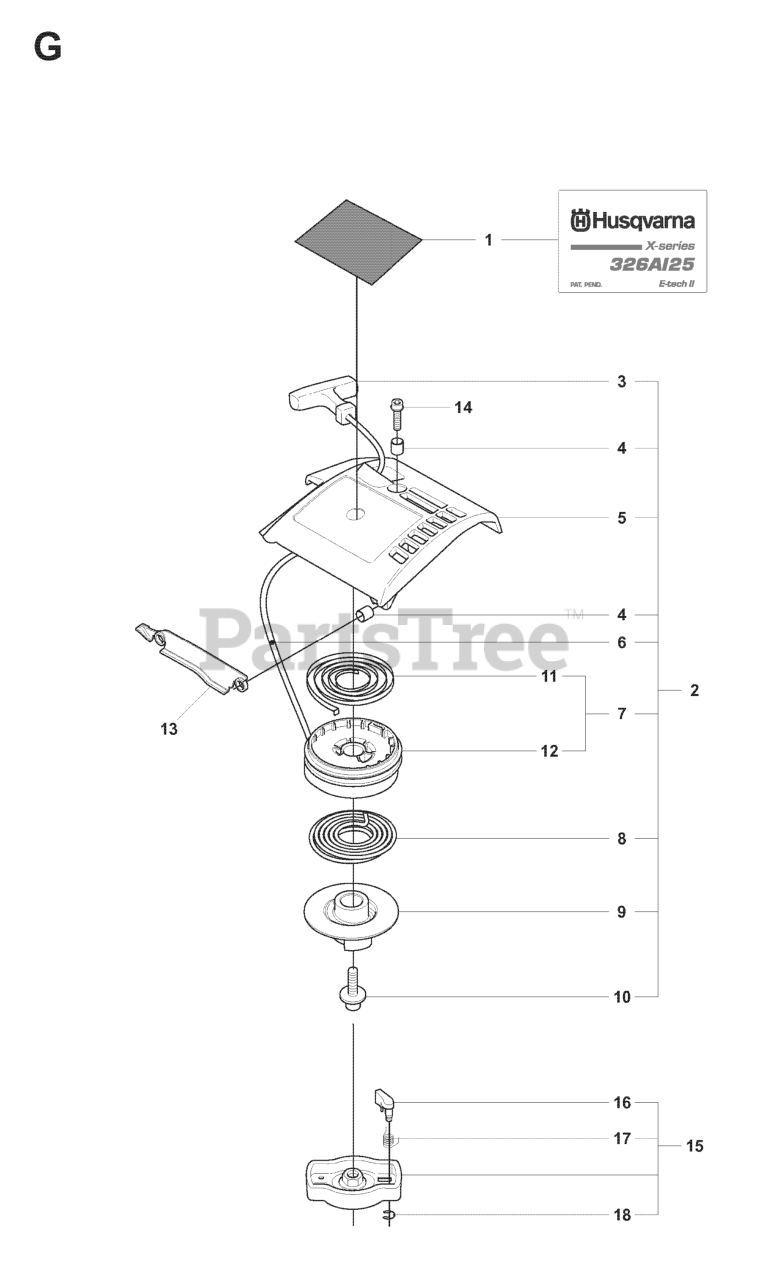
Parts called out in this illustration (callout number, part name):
1	LABEL 326AI
2	RP STARTER ASSY
3	STARTER HANDLE
4	SPACING SLEEVE
5	STARTER HOUSING
6	STARTER ROPE
7	STARTER PULLEY
8	SPRING - DRIVER
9	DRIVER PULLEY
12	STARTER PULLEY
15	STARTER PAWL BRIDGE
16	STARTER PAWL
